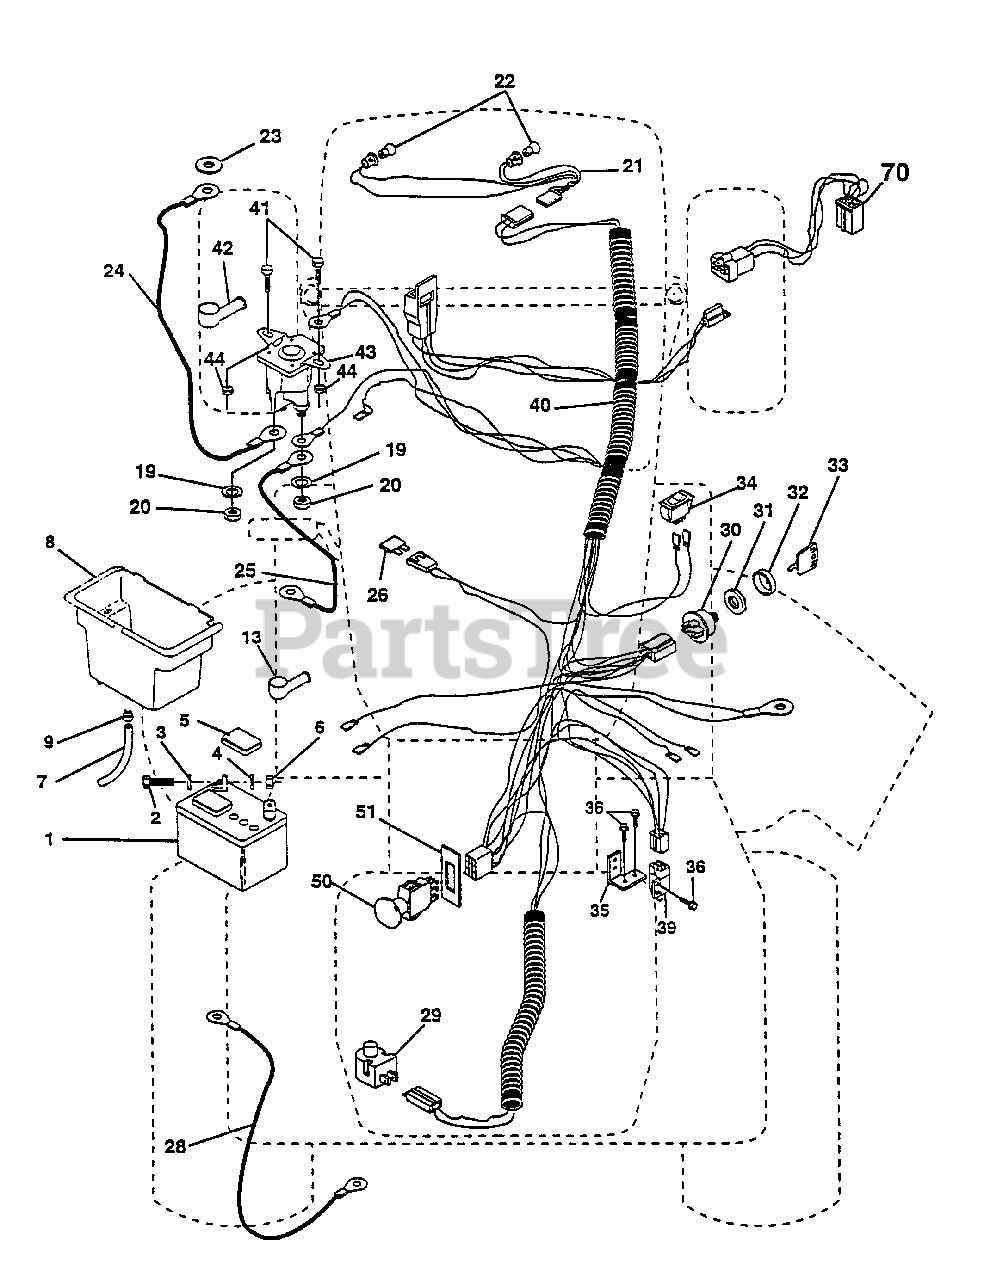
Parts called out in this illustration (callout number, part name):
1	Battery 12 Volt 30 Amp
2	Bolt Hex Hd 1/4-20unc X 3/4
3	Washer 9/32 X 5/8 X 16 Ga
4	Washer Lock Hvy Helical 1/4
5	Caps Battery 20/25/30 Amp
6	Nut Fin Hex 1/4-20 Unc
7	Tube Plastic 12"
8	Case Battery w/o Lid
9	Clamp Hose Olive
13	Cover, Terminal
19	Washer Lock 1 /4
20	Nut Jam Hex 1/4-20 Unc
21	Harness Socket Light
22	Bulb, Light # 1156
23	Washer, Lock Int. Tooth 1/4
24	Cable Battery 6ga 22" red
25	Cable Battery 6ga 39" Red
26	Fuse 30 Amp Auto Green
28	Cable Ground 6ga 12"black
29	Switch Plunger Nc Gray
30	Switch Ign 3 pos
31	Nut Ignition
32	Cover Sw Key
33	Key Ign Molded Generic
34	Switch Light BIk Blk Red
35	Bracket Switch Clutch
36	Screw Hex Tapping # 10-24 X 1/2
39	Switch Interlock Clutch
40	Harness Ign Kohl Fend HI Amm
41	Bolt Fin Hex 1/4-20uncxl/2 Gr5
42	Cover Terminal Red
43	Solenoid
44	Nut Keps Hex 1/4-20 Unc
45	Ammeter Rectangular
50	Swtitch PTO 3 pdt deltg
51	Ring Retainer PTO
70	Harness Engine Koh. cmd I.15AR
